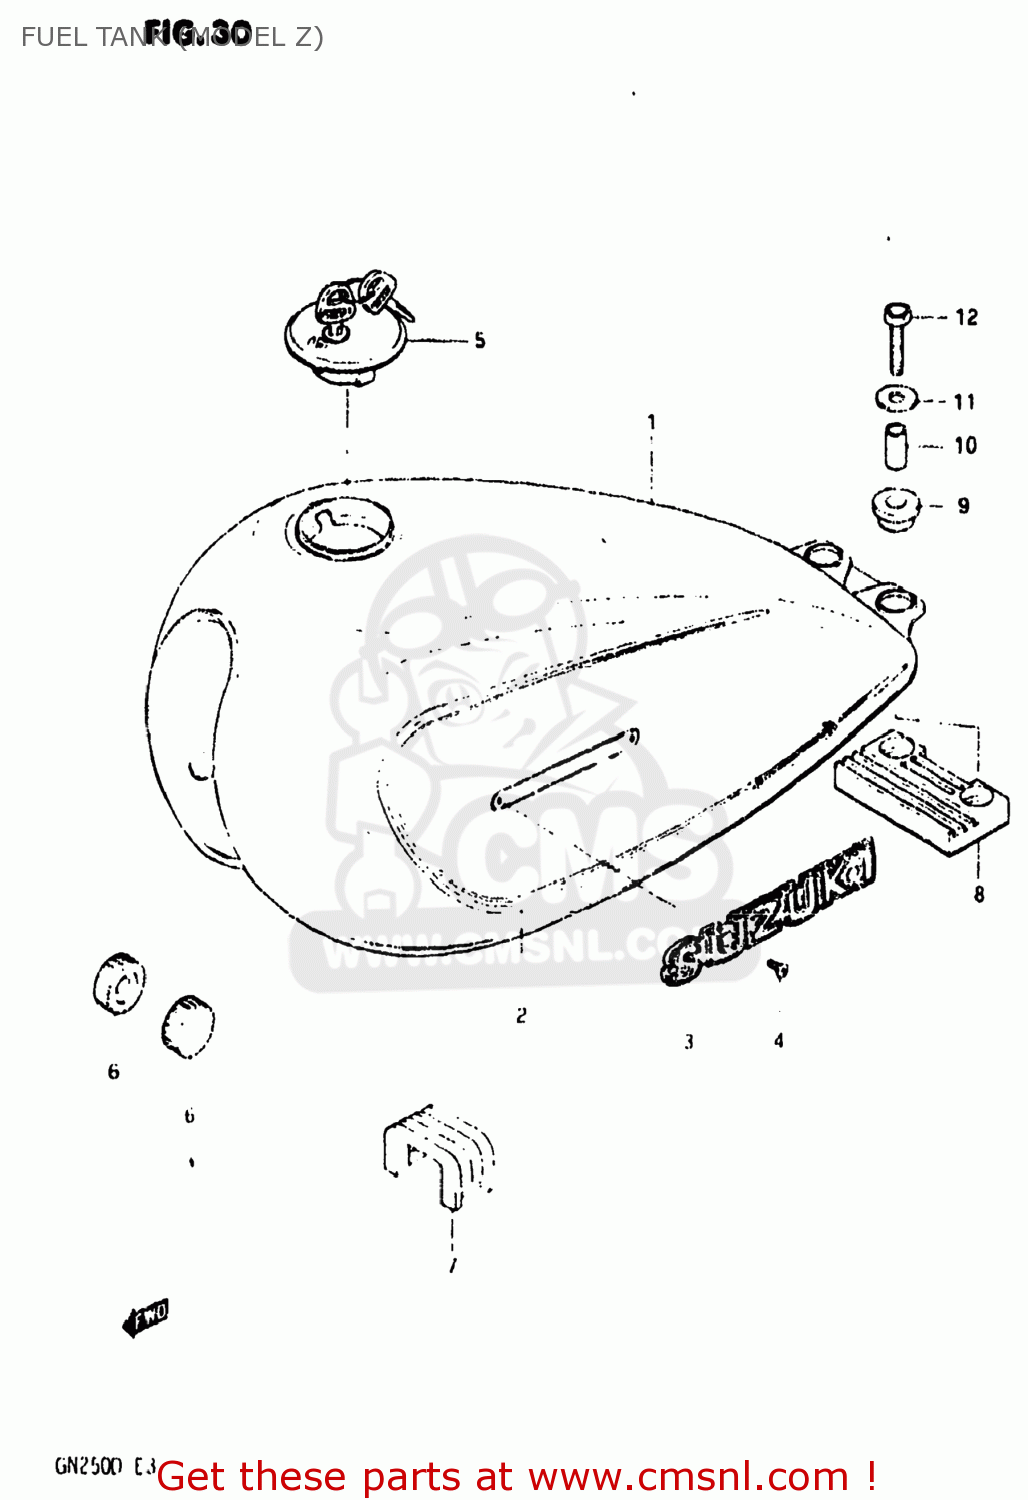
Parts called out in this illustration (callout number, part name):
1	TANK ASSEMBLY,FUEL
2	TAPE SET,FUEL TANK
3	EMBLEM,FUEL TANK
4	SCREW 3X6
5	CAP SET,FUEL TANK
6	CUSHION
7	CUSHION,TANK UPR FR
8	CUSHION,TANK RR NO.1
9	CUSHION
10	SPACER(6.5X10.5X22.5)
11	WASHER(6,5X22X1.6)
12	BOLT(6X35)
